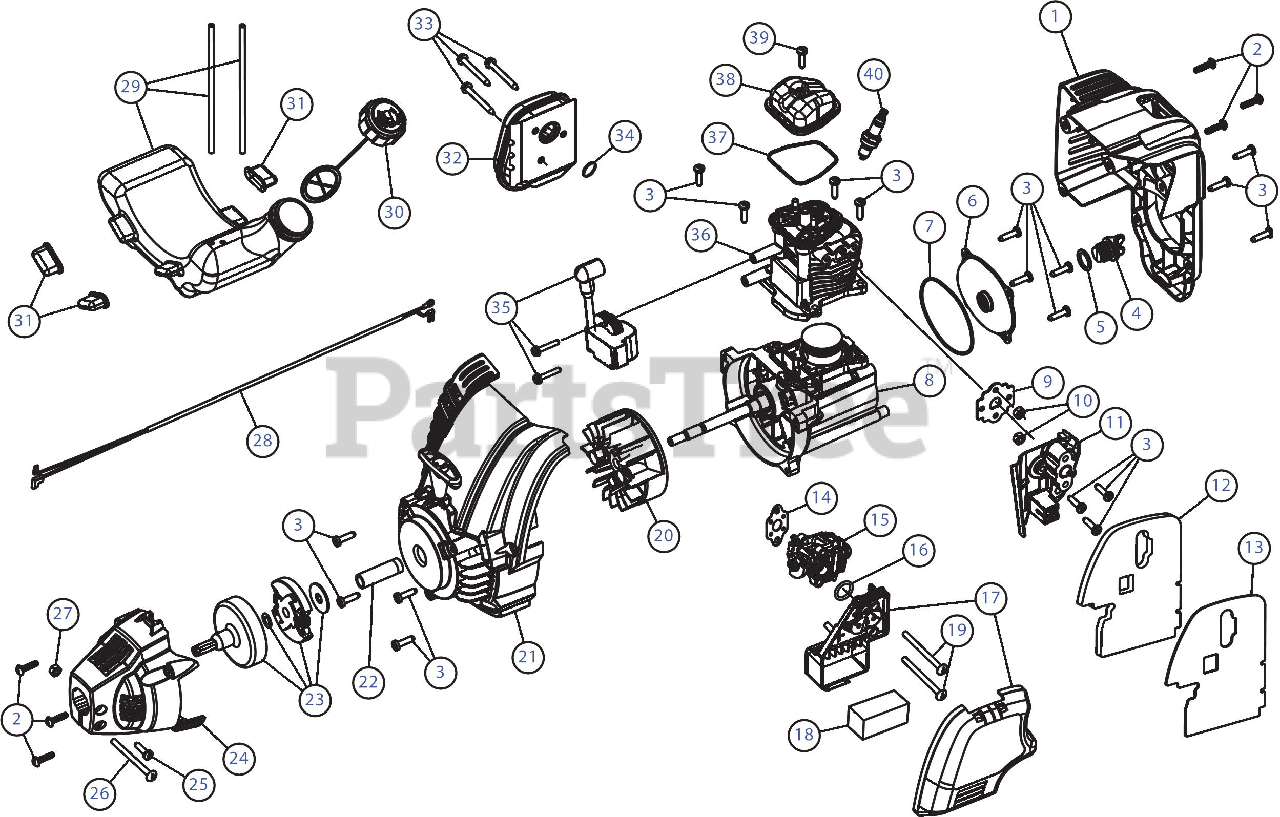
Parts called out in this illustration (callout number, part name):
1	Engine Cover Assembly (includes 2 & 3)
2	Cover Screw
4	Oil Plug (includes 5)
5	Oil Plug O-Ring
6	Crankcase Cover
7	Crankcase Cover O-Ring
8	Crankcase Assembly (includes 7)
9	Insulator Gasket
11	Insulator
12	Heat Shield
13	Gasket
15	Carburetor
17	Air Cleaner Cover Assembly (includes 18)
18	Air Filter
20	Flywheel Assembly
21	Starter Housing Assembly (includes 3)
22	Powershaft Spacer
23	Clutch Assembly
24	Clutch Cover (includes 2)
25	Anti-Rotation Screw
26	Clamp Screw
28	Lead Wires
29	Fuel Tank Assembly w/Fuel Lines (includes 30)
30	Fuel Tank Cap
31	Fuel Tank Pads
32	Muffler Assembly (includes 33 & 34)
33	Muffler Screw
34	Muffler Gasket
35	Module Assembly
36	Cylinder Assembly (includes 38 & 39)
37	Rocker Cover O-Ring
38	Rocker Cover
39	Rocker Cover Screw
40	Spark Plug
